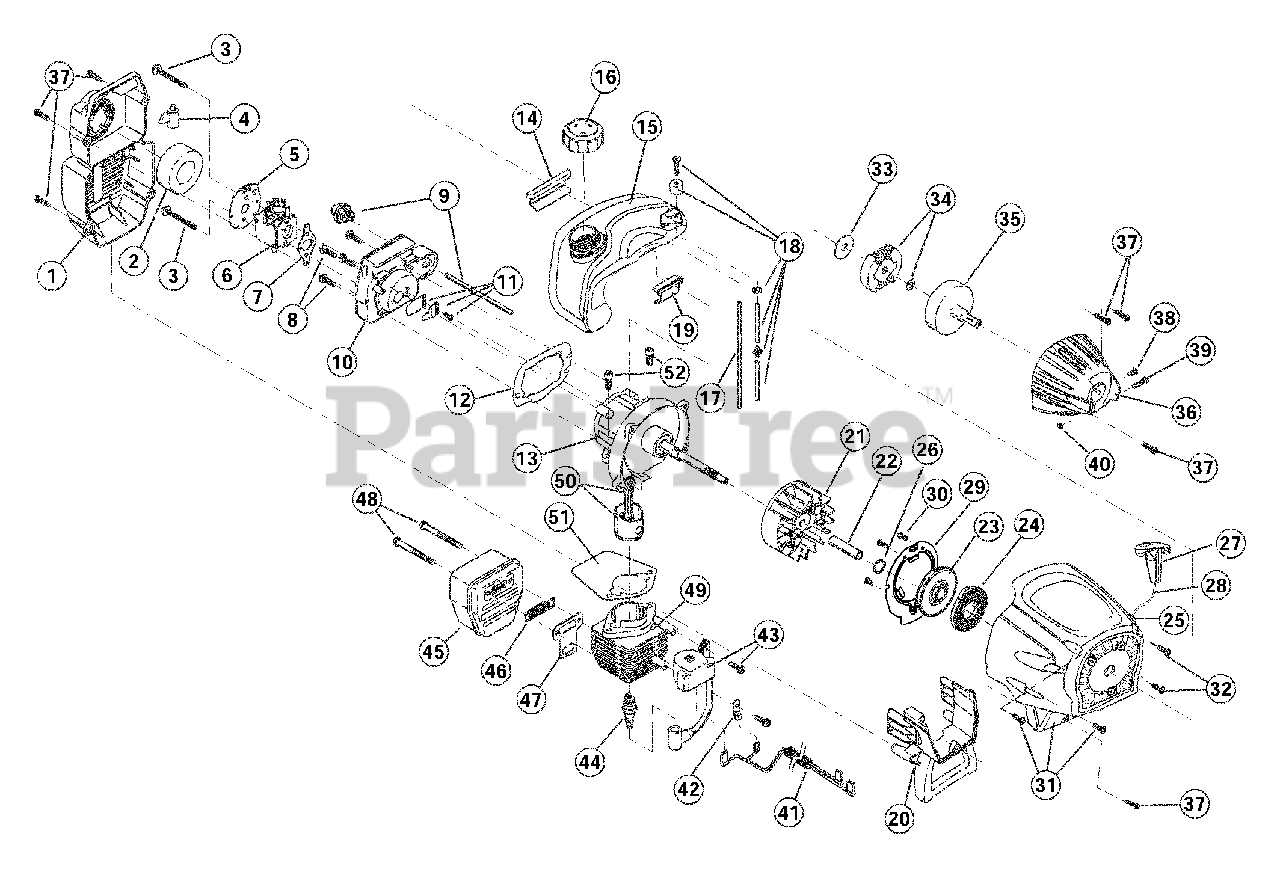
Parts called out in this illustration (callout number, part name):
1	Air Cleaner/Muffler Cover Assembly
2	Air Cleaner Filter
3	Carburetor Mounting Screws
4	Choke Extension
5	Choke Plate
6	Carburetor Assembly
7	Carburetor Gasket
8	Carb Mount Screw
9	Primer & Hose Assembly
10	Carb Mount Assembly
11	Reed Assembly
12	Carburetor Mount Gasket
13	Crank Case Service Assembly
14	Rear Mounting Pad
15	Fuel Tank Assembly
16	Fuel Cap Assembly
17	Fuel Return Line
18	Fuel Line Assembly
19	Front Mounting Pad
20	Shroud Extension & Stand
21	Flywheel Assembly
23	Spring Assist Pulley Assembly
24	Recoil Spring
25	Rope Guide
26	Pulley Retainer
27	Pull Handle
29	Pressure Plate Assembly
30	Plate Screw
31	Starter Housing Assembly
32	Housing Screw
33	Clutch Washer
34	Clutch Rotor Assembly
35	Clutch Drum Assembly
36	Clutch Cover Assembly
37	Cover Screw
38	Anti-Rotation Screw
39	Clamping Screw
40	Clamping Nut
41	Wire Leads & Sleeve
42	Ground Tab
43	Module Assembly
45	Muffler Assembly
46	Spark Arrestor Screen
47	Exhaust Gasket
48	Muffler Mounting Bolt Assembly
49	Cylinder Assembly
50	Piston and Rod Assembly
51	Cylinder Gasket
52	Cylinder Bolt
